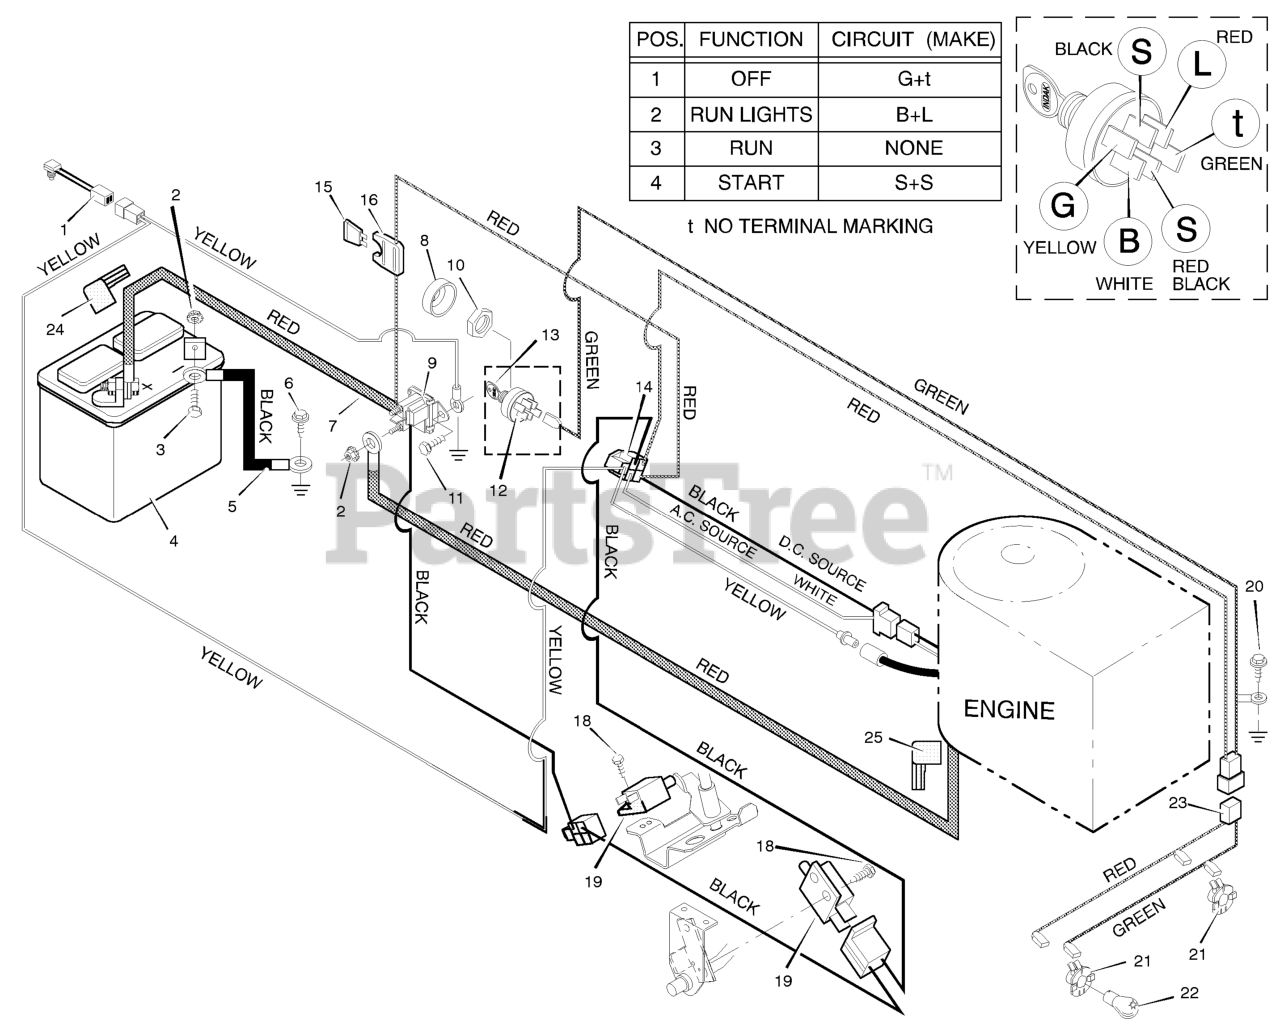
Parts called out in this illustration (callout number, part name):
1	Switch, Seat Sensor
2	Locknut
3	Bolt, Hex
4	Battery
5	Cable, Battery Ground
7	Cable, Red Battery
8	Cap, Ignition
9	Solenoid
10	Nut
12	Switch, Ignition
13	Key, Ignition
14	Harness, Chassis Wire
16	Holder, Fuse
19	Switch, Clutch
20	Screw
21	Socket, Light
22	Bulb, Light
23	Harness, Light Wire
24	Cover, Terminal
